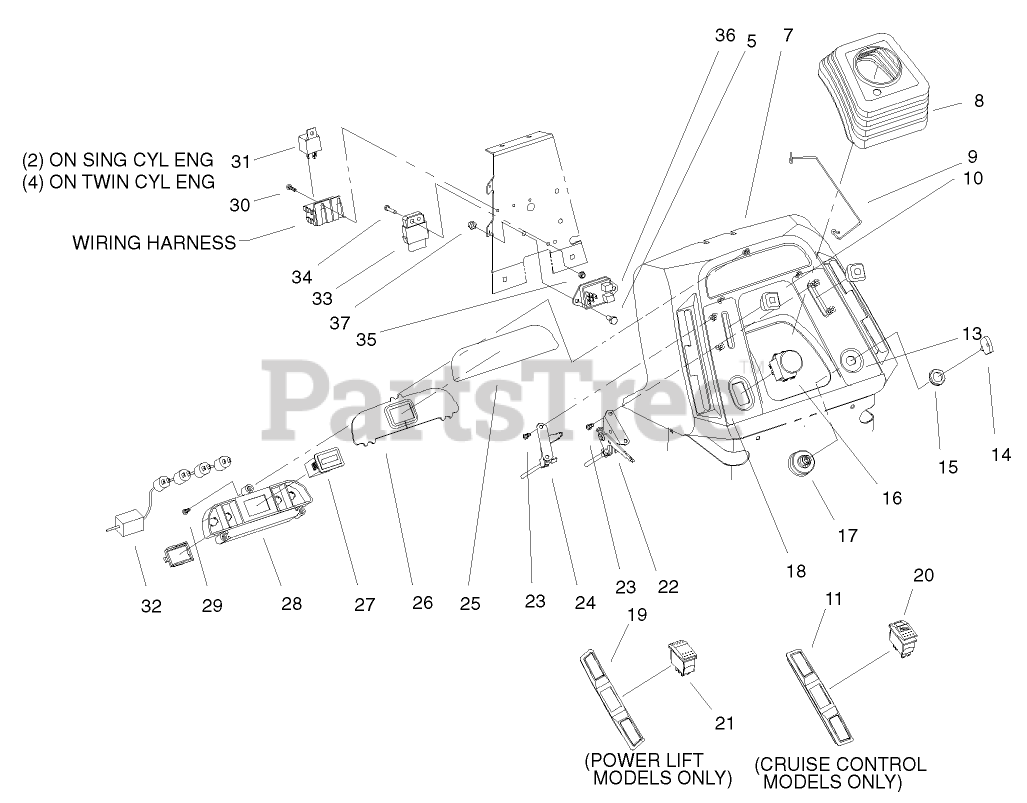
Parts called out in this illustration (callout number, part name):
5	SCREW-HH
8	BOOT-STEERING
9	CLIP-BOOT
11	COVER-SLOT, RH
13	DECAL-THROTTLE, IGNITION
13	DECAL-DASH
14	KEY-IGNITION
16	SWITCH-PTO,ON-ON-NONE
17	SWITCH-IGNITION
18	DECAL-DASH, PTO/CHOKE
18	DECAL-PTO / CHOKE
19	COVER-LIFT
20	SWITCH-CRUISE
21	SWITCH
22	CONTROL-THROTTLE (TWIN)
24	CONTROL-CHOKE (TWIN)
25	DECAL - DASH LENS
26	LENS-DASH
27	HOURMETER
28	HOUSING-LIGHT
29	SCREW
30	SCREW-PPHTF
31	RELAY
32	HARNESS-6 LAMP
33	MODULE-LOW VOLTAGE
35	NUT-LOCK, NI
36	MODULE-CLUTCH
37	NUT-LOCK, NI
